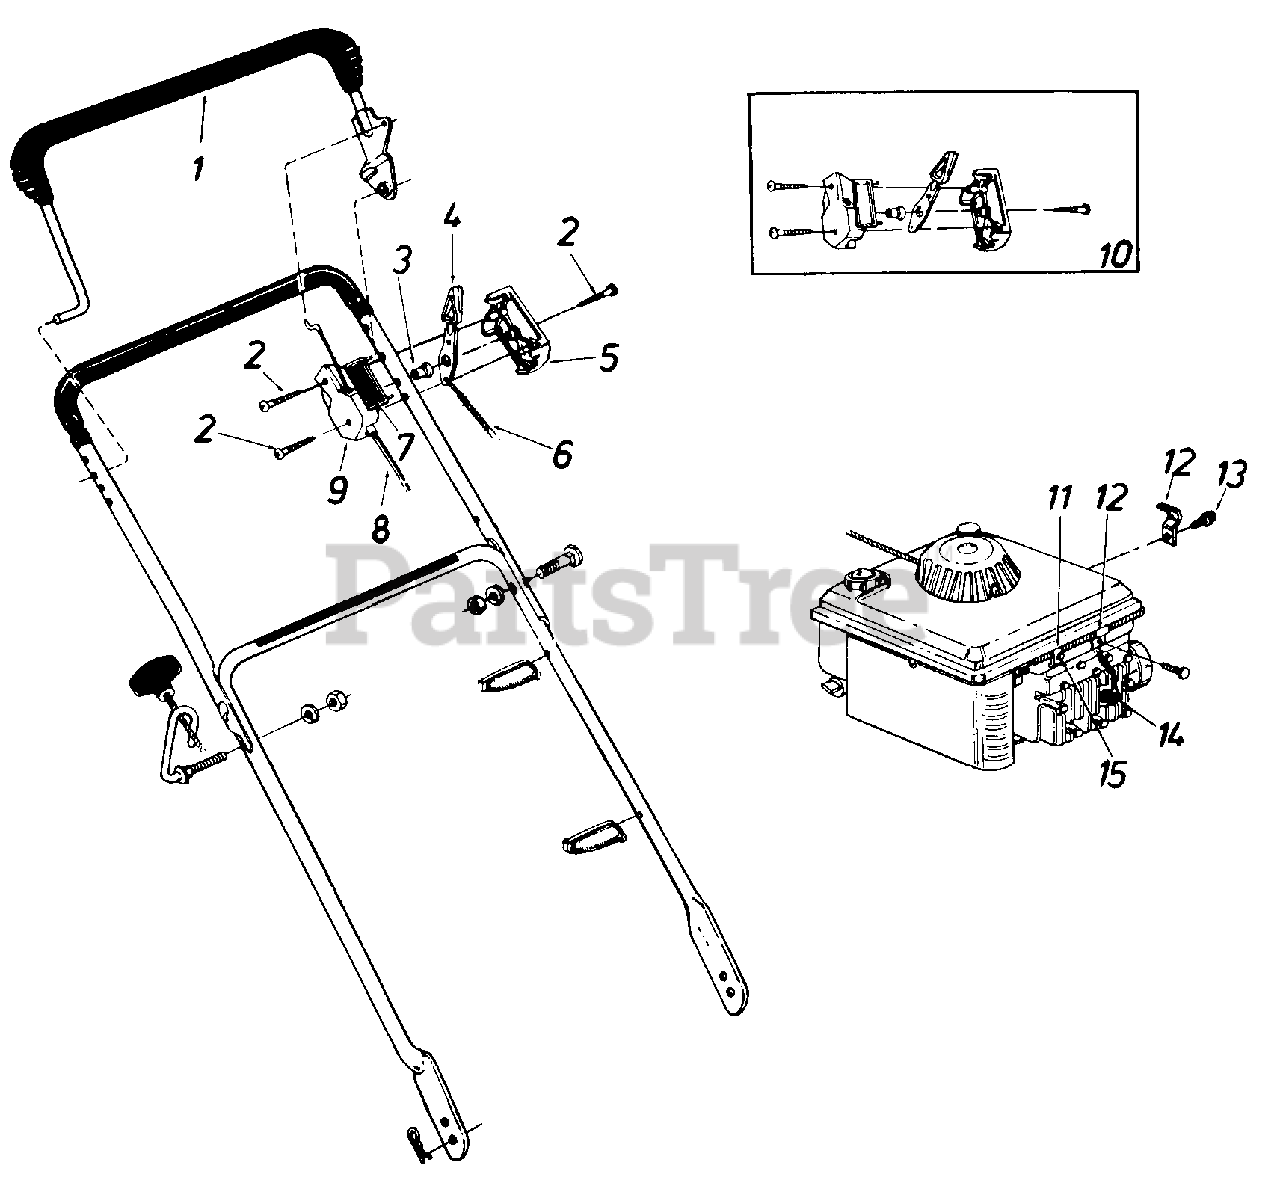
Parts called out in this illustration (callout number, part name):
1	Control Handle Ass'y.
2	Truss Mach. Scr. #12 x 1.5" Lg.
3	Control Disc Pin
4	Throttle Control Lever
5	Control Panel Half
6	Throttle Control Wire-53"
7	Control Label
8	Control Cable-43"
9	Clutch Panel Half
10	Control Housing Comp.
11	Casing Clamp
12	Casing Clamp
13	Hex B-Tap Scr. #10 x .38" Lg.
14	Spark Plug Insulator
15	Hex B-TaP Scr. #10 x .62" Lg.
